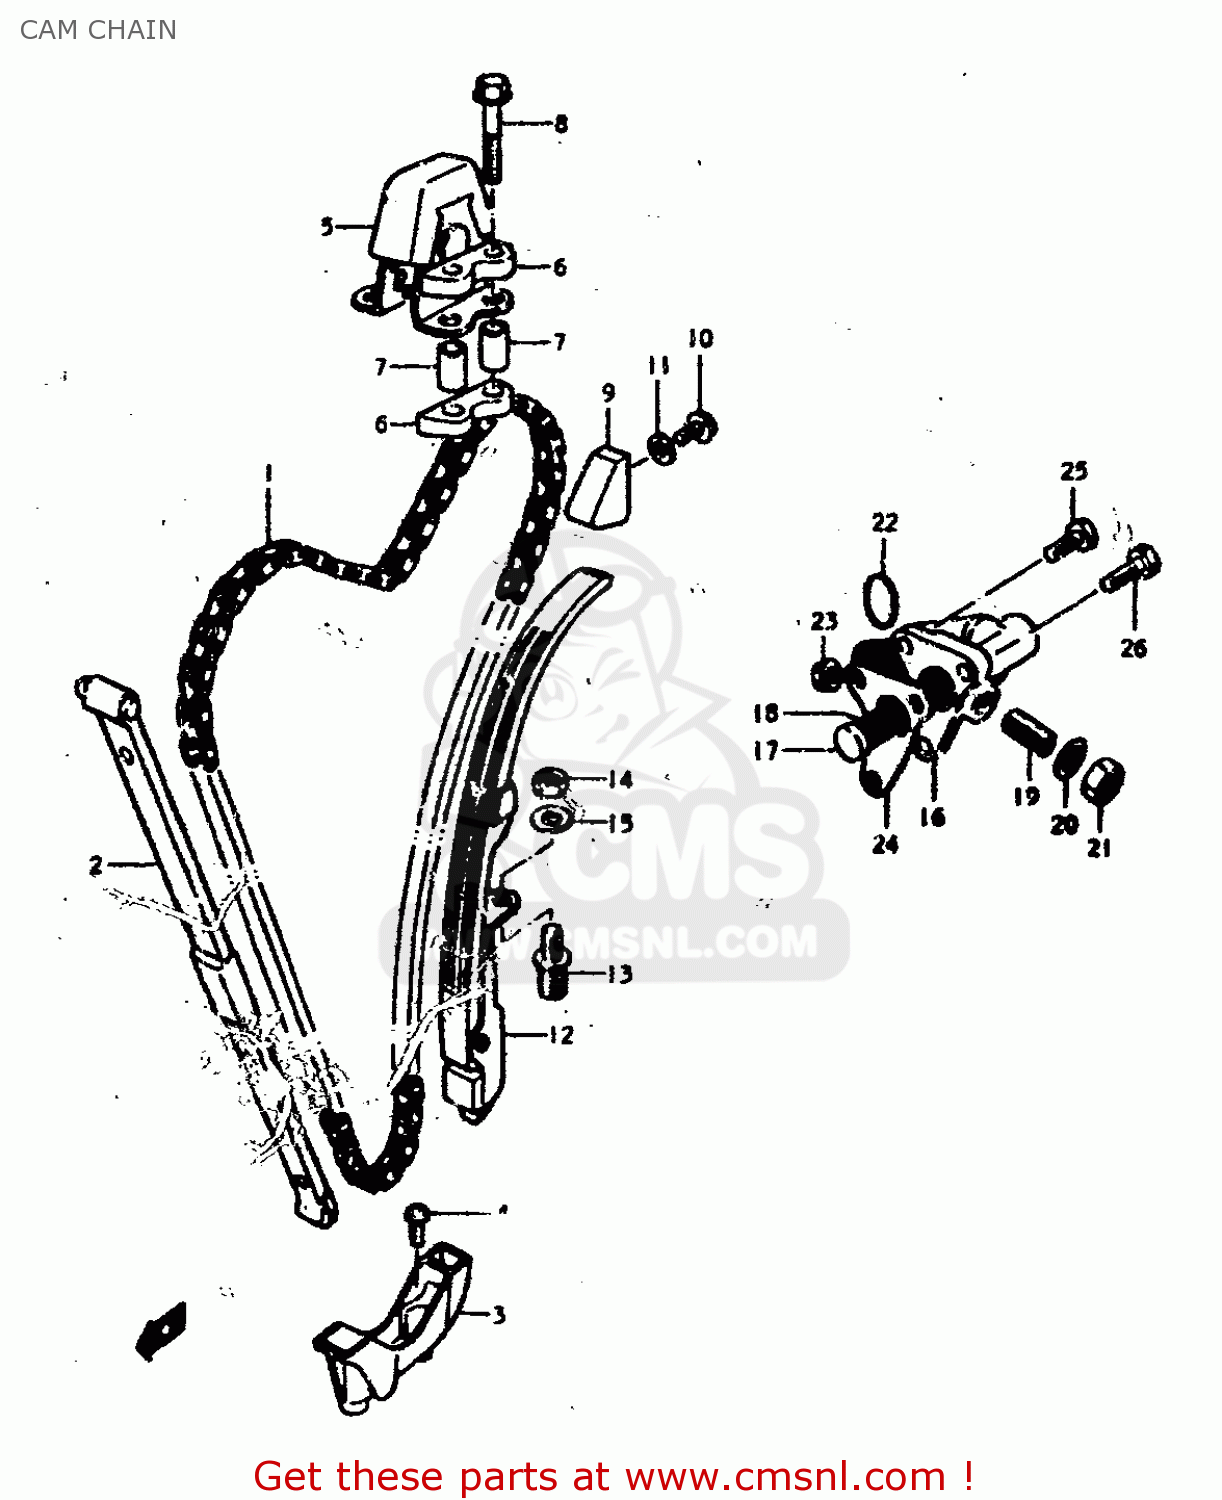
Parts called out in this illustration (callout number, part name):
1	CHAIN,CAMSHAFT DRIVE(120L)
2	GUIDE,CAM CHAIN
3	HOLDER,CAM CHAIN GUIDE
4	SCREW
5	IDLER,CAM CHAIN
6	CUSHION,IDLER
7	SPACER
8	BOLT
9	GUIDE,CAM CHAIN
10	BOLT
11	GASKET (NAS)
12	TENSIONER,CAM CHAIN
13	STUD
14	NUT 8MM
15	WASHER
16	ADJUSTER ASSEMBLY,TENSIONER
17	ROD,PUSH
18	SPRING
19	SCREW
20	WASHER
21	NUT
22	O-RING
23	NUT
24	GASKET,TENSIONER ADJUSTER (MCA)
25	SCREW
26	SCREW
